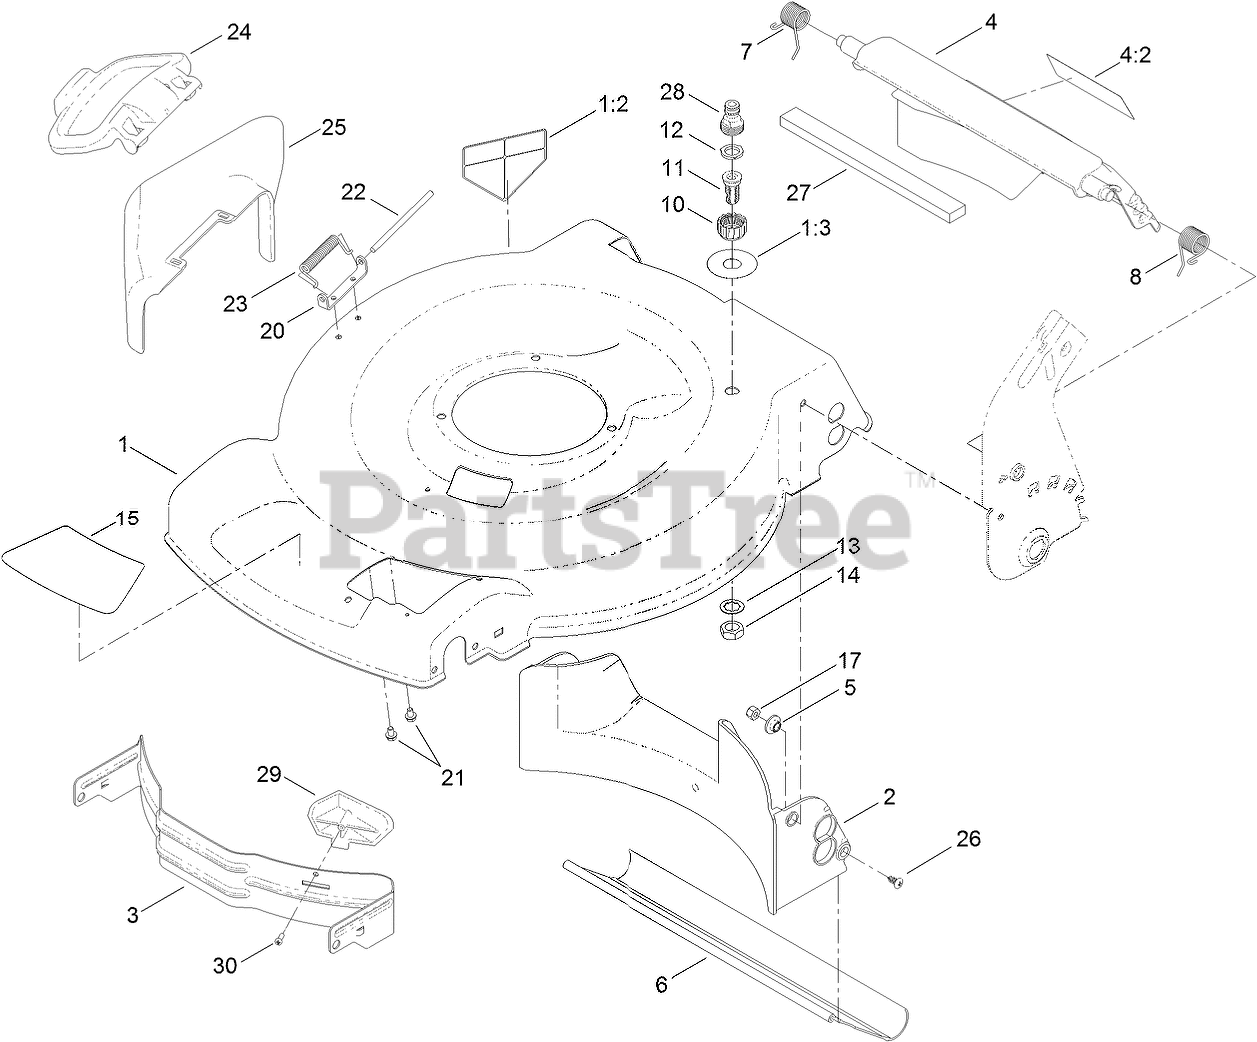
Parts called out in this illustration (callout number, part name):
1	HOUSING ASM
1:2	DECAL-DANGER
1:3	DECAL-PORT, WASHOUT
2	BAFFLE-REAR
3	BAFFLE-FRONT
4	REAR DEFLECTOR ASM
4:2	DECAL-WARNING
5	WASHER-STEPPED, BAFFLE
6	SHIELD-TRAILING
7	SPRING-TORSION
8	SPRING-TORSION
10	COUPLING-HOSE, WASHOUT PORT
11	PORT-WASHOUT
12	WASHER-SEAL, WASHOUT PORT
13	WASHER-TOOTH, INTERNAL
14	NUT-JAM
15	DECAL-DECK
17	NUT-LOCK, NI
20	BRACKET-COVER
21	SCREW-HWH
22	ROD-COVER
23	SPRING-TORSION
24	DEFLECTOR-SIDE
25	CHUTE-DISCHARGE, SIDE
26	SCREW-PTH
27	FOAM-SEAL
28	ADAPTER-CONNECT, QUICK
29	KICKER-FRONT
30	SCREW-PPH
